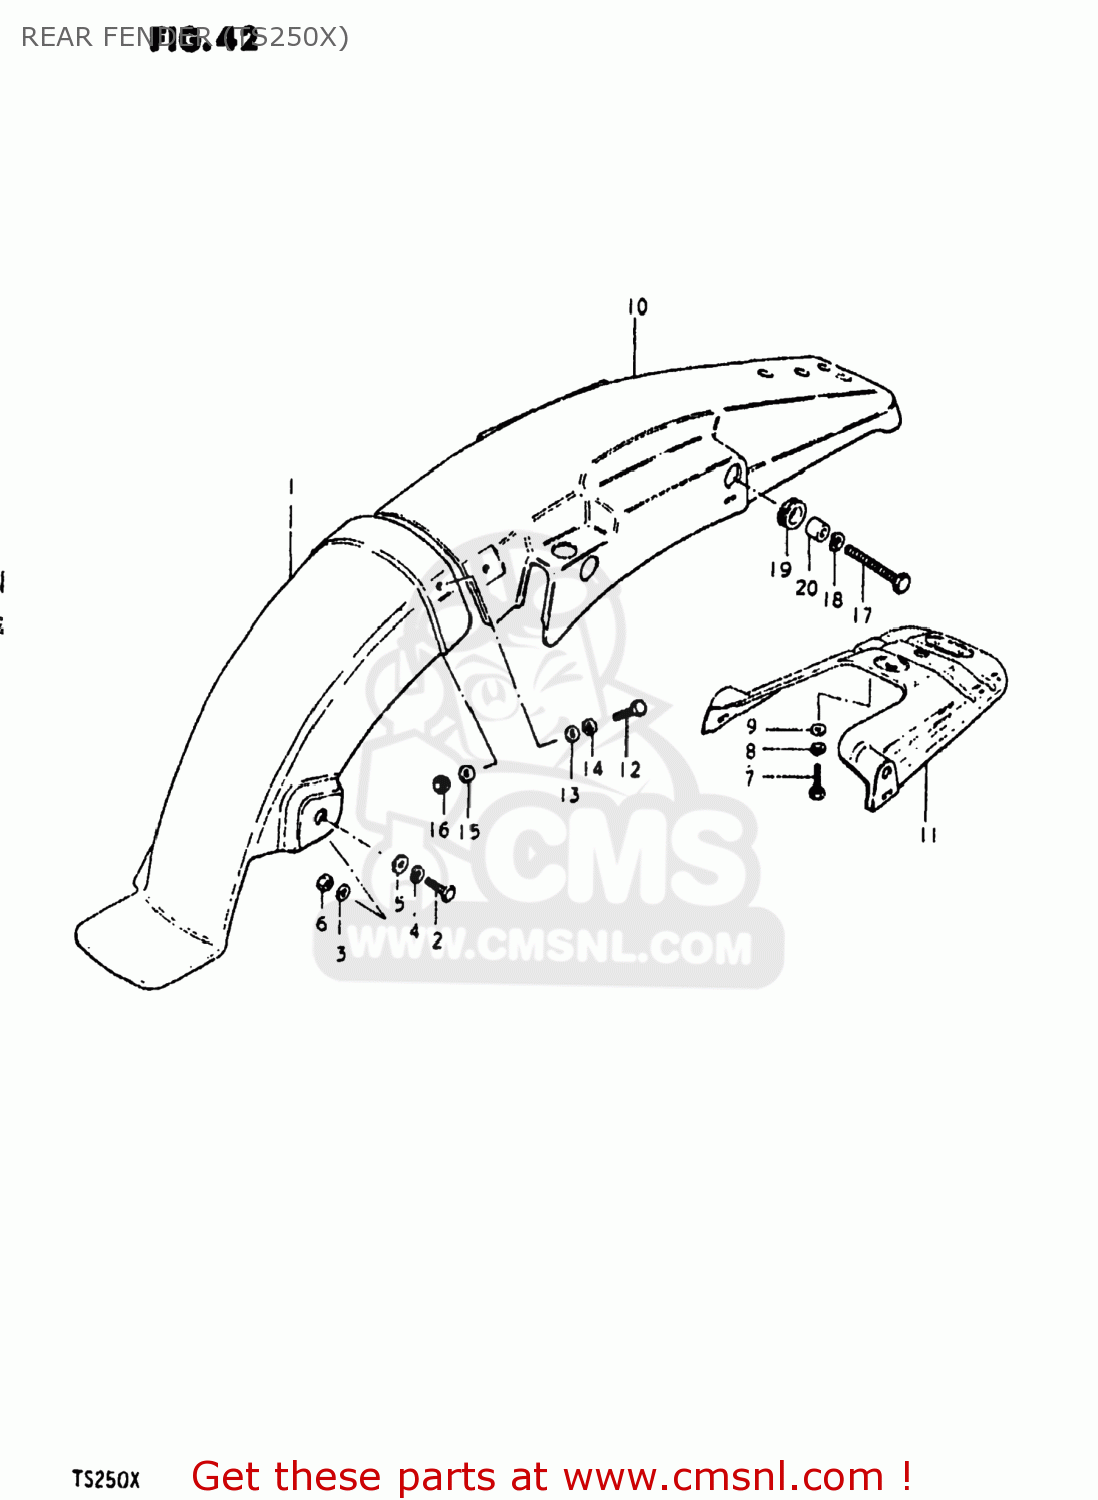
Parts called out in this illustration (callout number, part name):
1	FENDER,REAR
2	BOLT, UPPER
3	WASHER
4	LOCK WASHER
5	WASHER
6	NUT
7	BOLT
8	LOCK WASHER
9	WASHER
10	FENDER,REAR
11	REINFORCEMENT,REAR FENDER
12	BOLT
13	WASHER (5.5X16X1.2)
14	LOCK WASHER
15	WASHER(5.2X16X1)
16	NUT
17	BOLT (8X30)
18	LOCK WASHER
19	CUSHION
20	SPACER (8.2X12X7.5)
